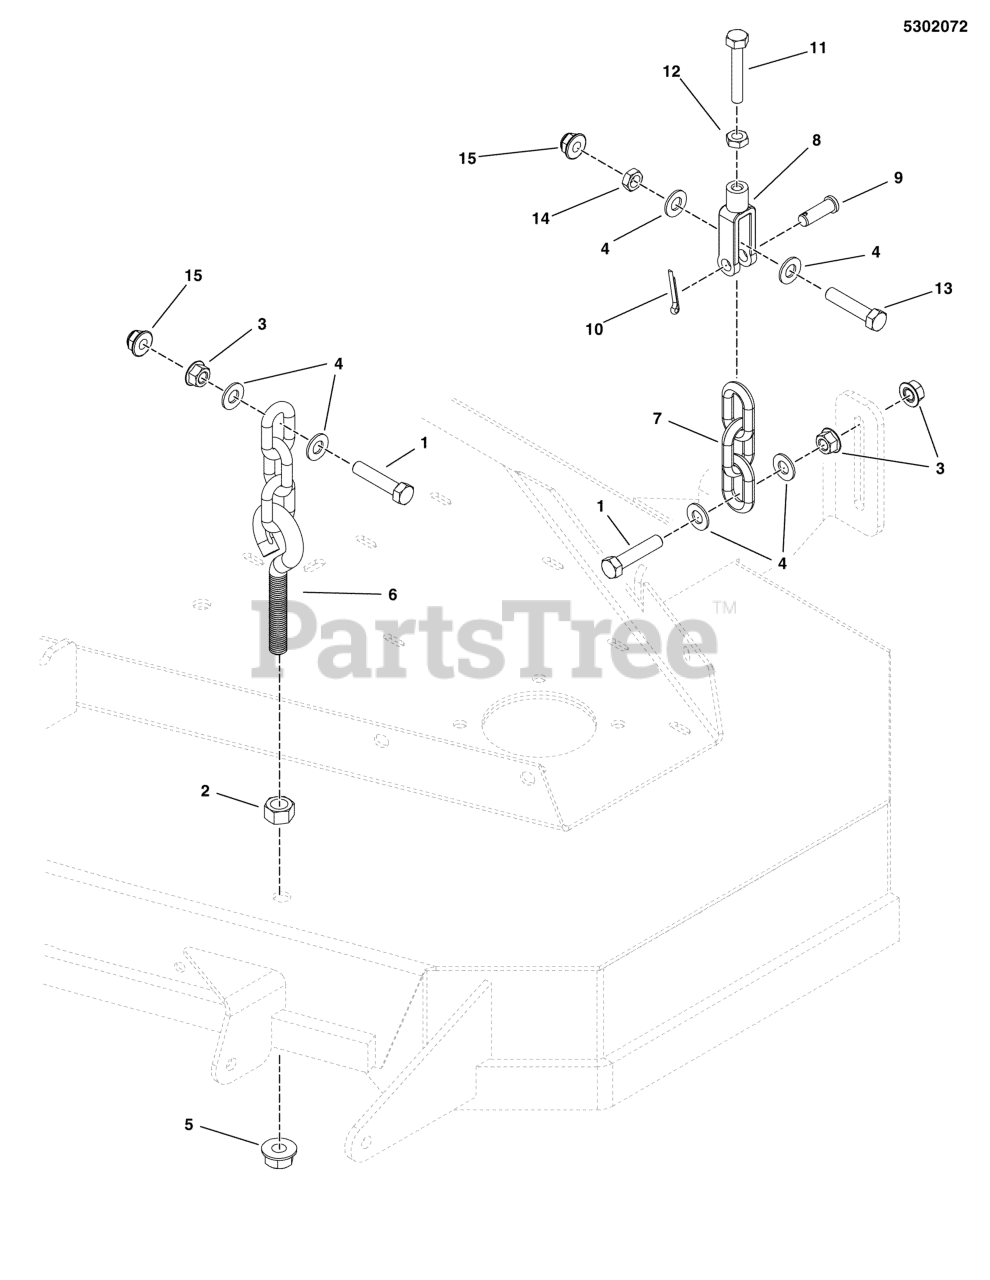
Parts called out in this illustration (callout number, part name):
1	BOLT, 3/8-16 X 1-3/4" GD5 CZ
2	NUT, 1/2-13 HEX, YZ
3	NUT, 3/8-16 HEX SERRATED FLANGE
4	WASHER, 3/8 SAE
5	NUT, Hex Flange, Nylock, 1/2-13
6	HANGER, FRONT DECK - 4 LINK, 5.5" EB
7	CHAIN, 5/16 GD30, 3 LINKS
8	CLEVIS, 5/16-18, 3/8 PIN HOLE
9	PIN, CLEVIS, 3/8 X 1-1/8, YZ
10	PIN, COTTER, 1/8 X 1-1/4
11	BOLT, 5/16-18 X 2 GD5 TFL
12	NUT, 5/16-18 HEX JAM
13	BOLT, 3/8-16 X 2, GD5, CZ
14	NUT, 3/8-16 HEX JAM
15	NUT, 3/8-16 HEX NYLOCK FLANGE
